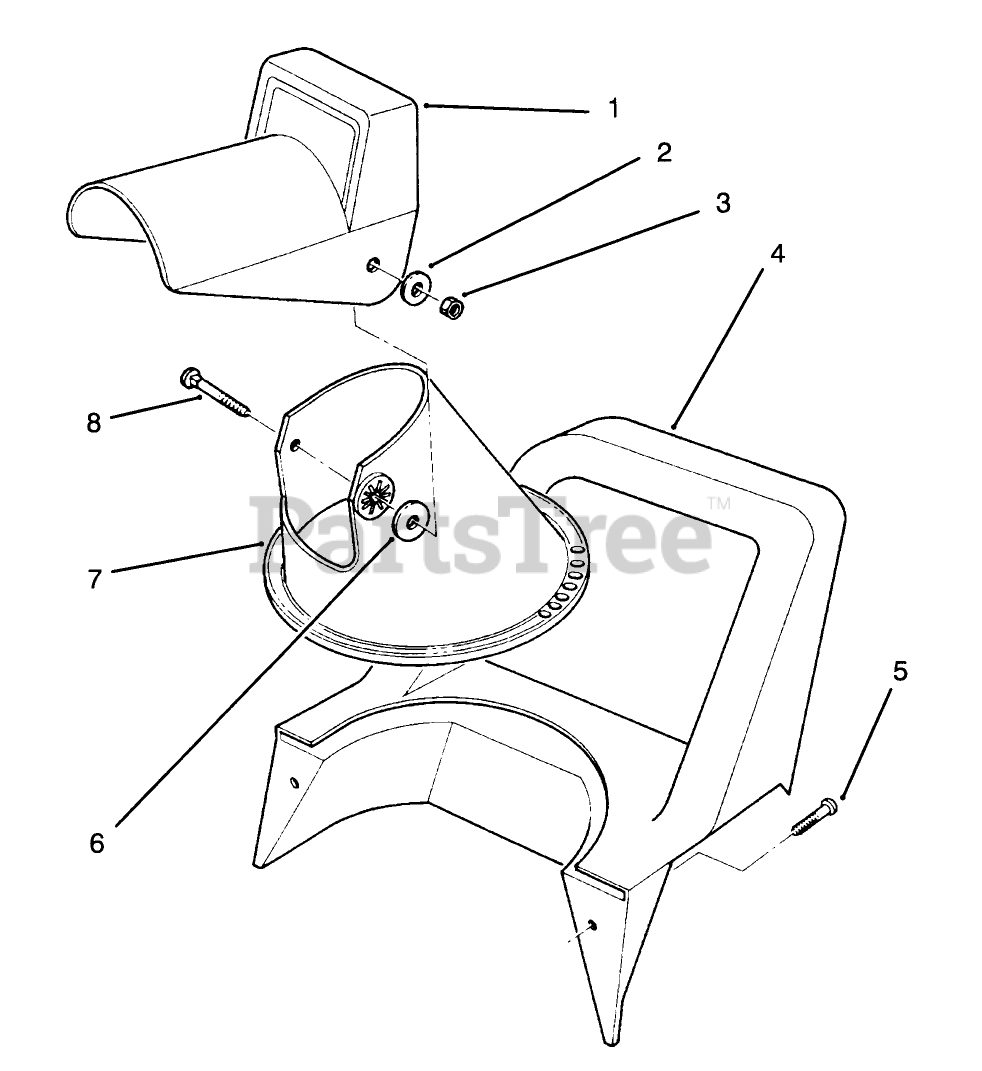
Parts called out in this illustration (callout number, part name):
1	CHUTE-DEFLECTOR
2	WASHER-FLAT
3	NUT-LOCK, NI
4	MIDDLE HANDLE - 1800
6	WASHER-RUBBER
7	LOWER CHUTE, 1800
8	BOLT-CARR
